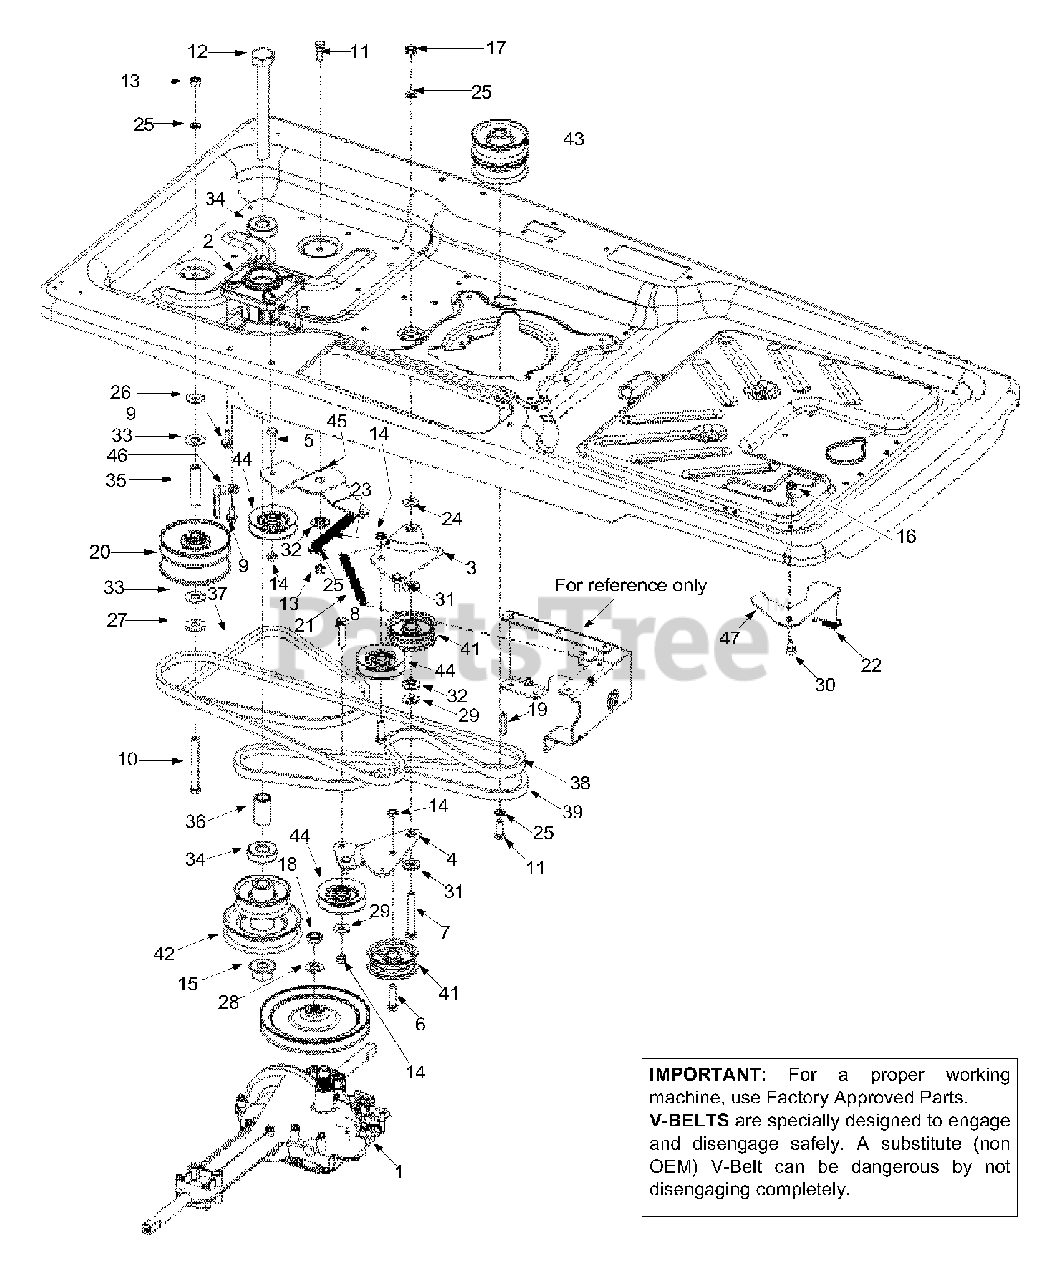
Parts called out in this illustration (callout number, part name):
1	Transmission Assembly
2	Spindle Housing
3	Idler Bracket Assembly
4	Idler Bracket Assembly
5	Hex Bolt 3/8-24 x 1.25"
6	Hex Bolt 3/8-24 x 1.50"
7	Hex Bolt 3/8-16 x 3.0"
8	Hex Bolt 3/8-24 x 1.75"
9	TT Screw 5/16-18 x 0.875"
10	Hex Screw 3/8-24 x 3.75"
11	Hex Screw 3/8-24 x 1.0"
12	Hex Screw M20 x 2.5:180
13	Hex Nut 3/8-24
14	Jam Lock Nut 3/8-24
15	Hex Flange Nut M20 x 2.5
16	Flange Lock Nut 5/16-18
17	Hex Nut 3/8-16
18	Jam Nut 9/16-18
20	Variable Speed Pulley Assembly
21	Extension Spring
22	Extension Spring
23	Extension Spring
24	Flat Washer .406 x 1.0 x .030
25	Lock Washer 3/8
26	Bell Washer .39 x 1.13 x .062
27	Flat Washer 3/8 x 1.25"
28	Bell Washer .567 x 1.125 x .06
29	Flat Washer .406 x 1.0 x .105
30	Shoulder Screw
31	Shoulder Spacer
32	Shoulder Spacer
33	Thrust Bearing
34	Ball Bearing
35	Sleeve Spacer
36	Spacer
37	Belt: V Type
38	Belt: V Type
39	Belt: V Type
41	Flat Idler Pulley
42	Jack Pulley: Double
43	Engine Pulley: Double
44	Idler Pulley
45	Idler Bracket: Variable Speed
46	Cable Bracket
47	Bracket: Lock: Pedal
